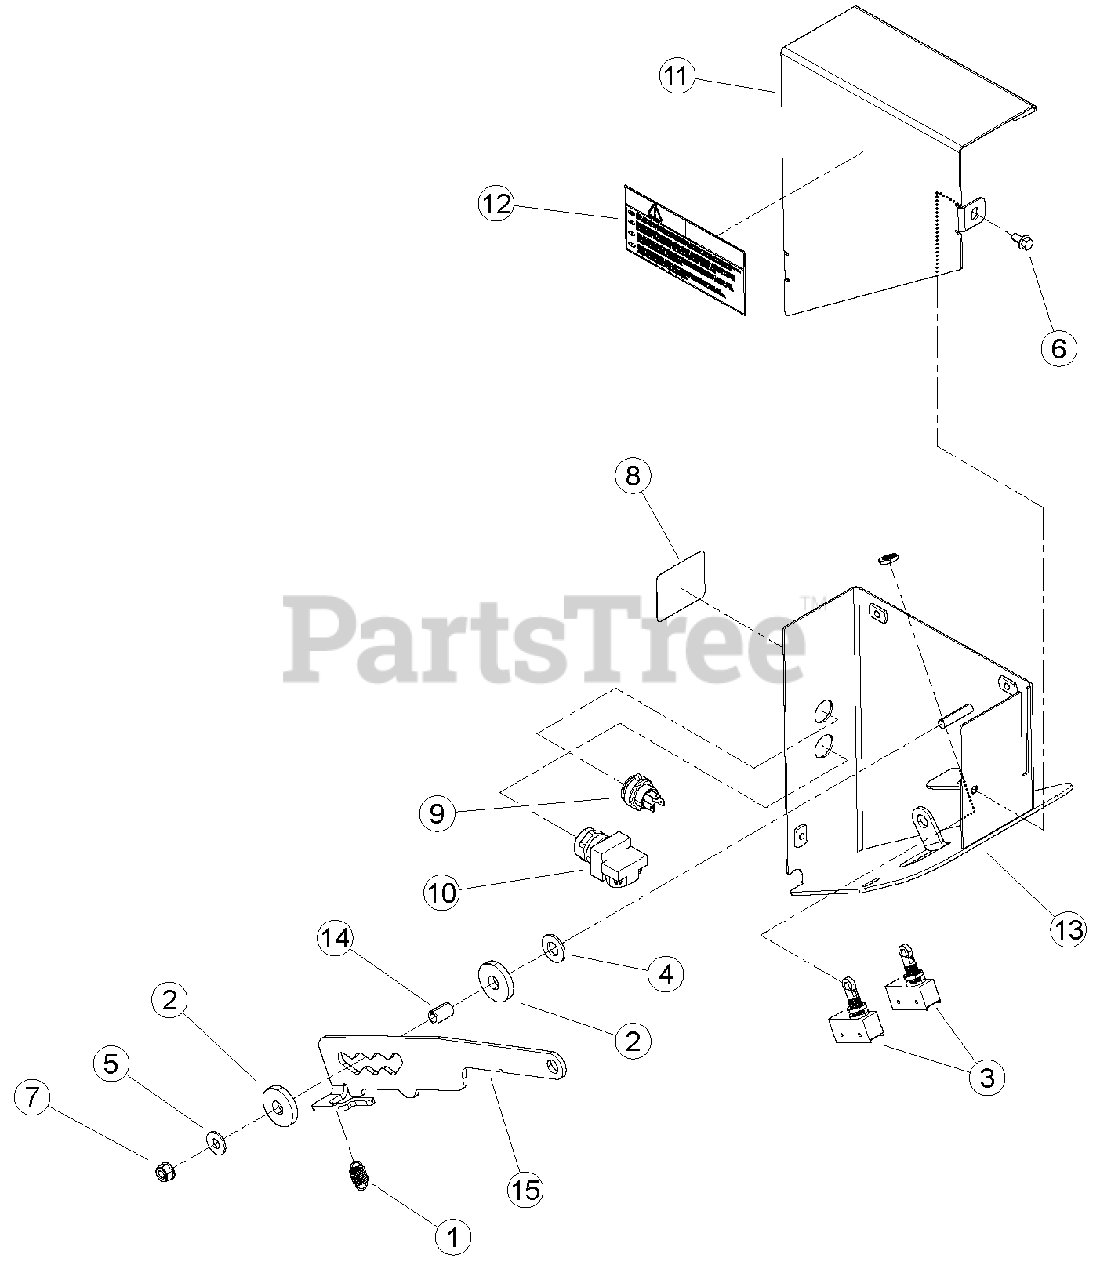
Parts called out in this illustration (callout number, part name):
1	SPRING, CONTROL BAR
2	WASHER, UHMW SPACER .515ID-1.50OD
3	SWITCH, FEED CONTROL
4	WASHER, 1/2" SAE FLAT ZP
5	WASHER, 5/16" FLAT ZP
6	BOLT, 1/4 X 1/2" SERRATED FLANGE GR5 ZP
7	NUT, 5/16-18 NYLOCK-FLANGE
8	DECAL, RESET/OVERRIDE
9	LIGHT, LED TRI-COLOR
10	SWITCH, MOMENTARY IP65 NORMALLY OFF
11	ASSEMBLY, 5" CONTROL COVER W/ DECAL, SERVICE PART
12	DECAL, MULTILINGUAL MANUAL
13	WELDMENT, XE CONTROL BOX
14	SPACER, .50 X .775
15	BAR, SWITCH CONTROL
